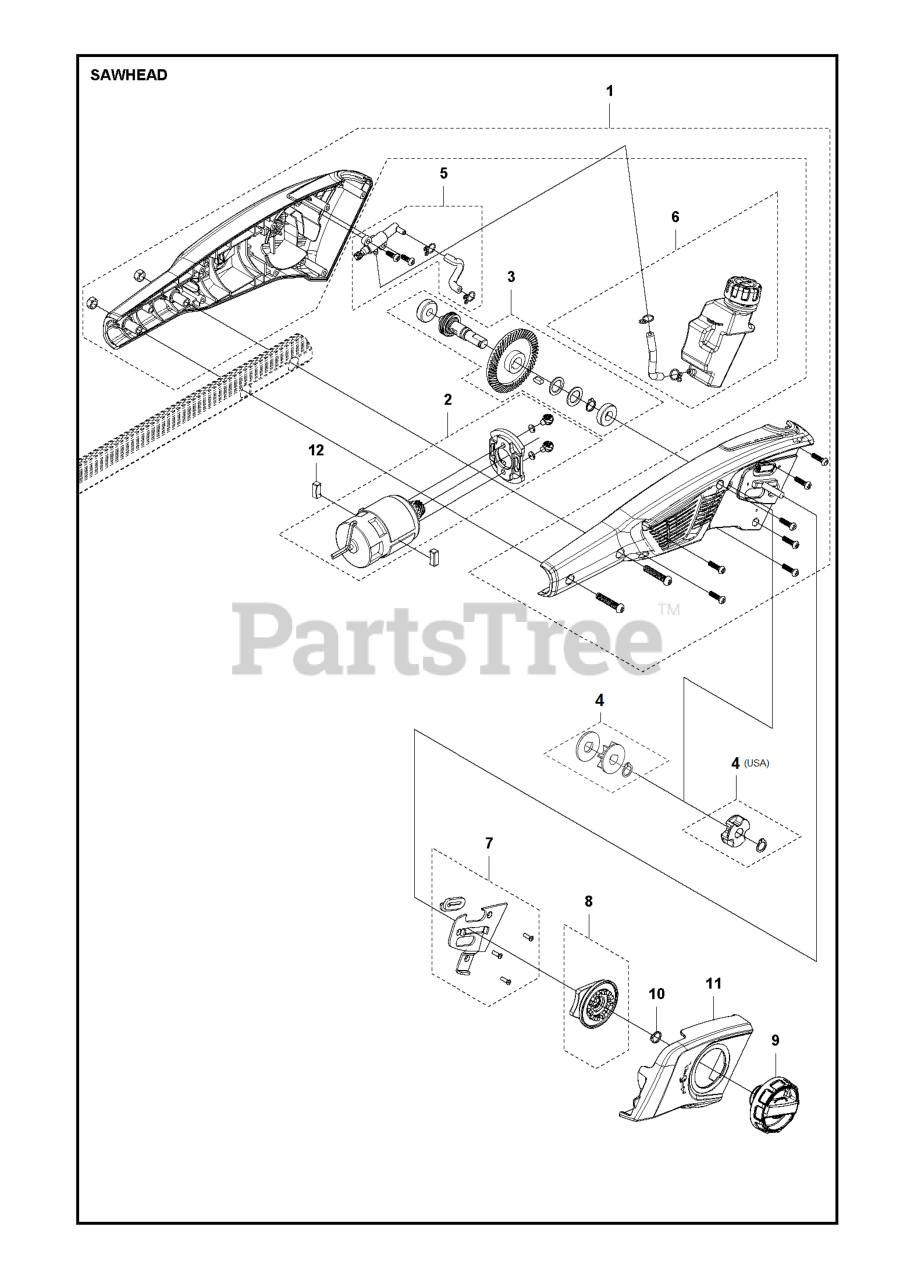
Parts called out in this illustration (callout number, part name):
1	COVER ASSY HEAD
2	MOTOR ASSY
4	SPROCKET CHAIN
5	OIL PUMP ASSY
7	MOUNTING PLATE ASSY
8	TENSIONER ASSY
9	KNOB ASSY LOKING
11	COVER UPPER
12	PLATE RUBBER
